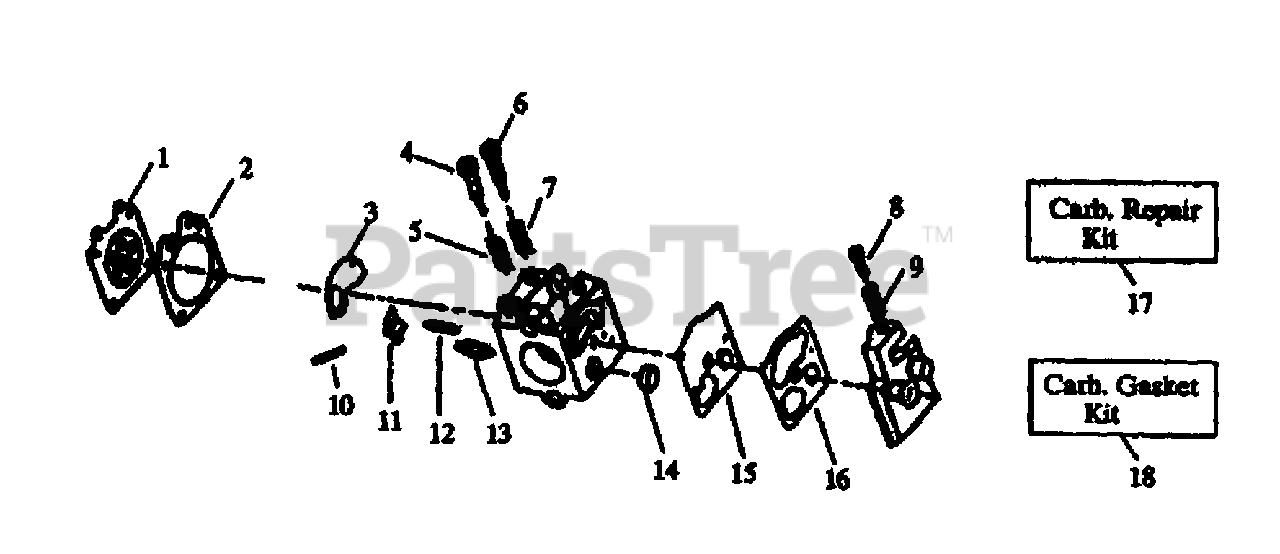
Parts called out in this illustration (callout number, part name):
1	Metering Diaphragm
2	Metering Diaphragm Gasket
3	Circuit Gasket
4	Hi Speed Needle
5	Hi Speed Needle Spring
6	Idle Needle
7	Idle Needle Spring
8	Idle Speed Screw
9	Idle Speed Spring
10	Metering Lever Pin
11	Metering Lever
12	Metering Lever Spring
13	Inlet Needle Valve
14	Inlet Screen
15	Pump Diaphram
16	Pump Gasket
17	Carb. Kwik Repair Kit
18	Carb. Gasket/Diaphragm Kit
